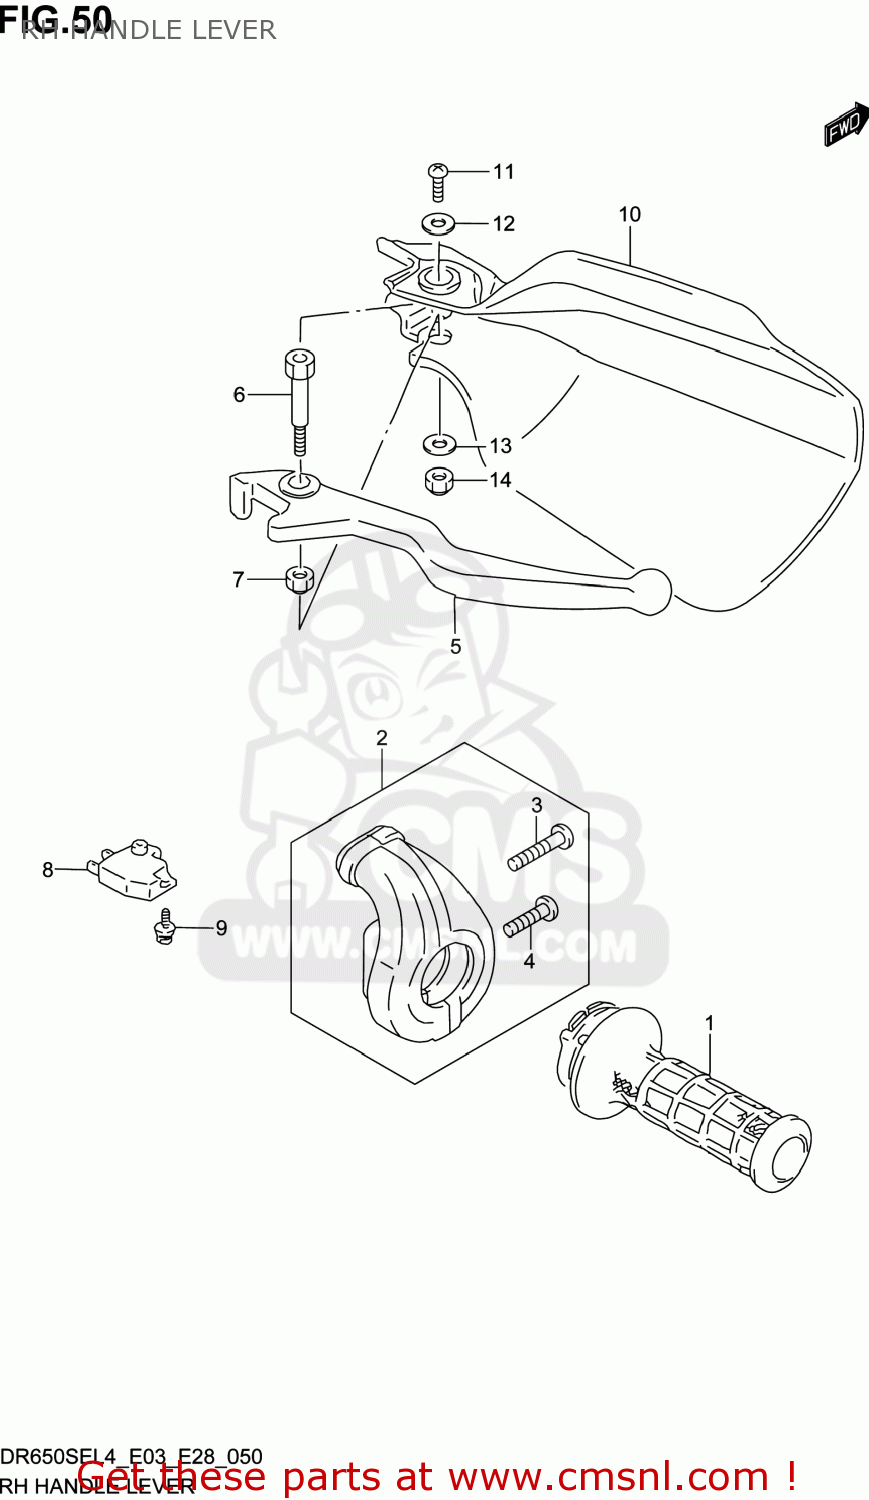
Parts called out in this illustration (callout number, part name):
1	GRIP,THROTTLE
2	CASE ASSY,THROTTLE
3	SCREW
4	SCREW
5	LEVER,BRAKE
6	BOLT,BRAKE LEVER PIVOT
7	NUT,LEVER PIVOT
8	SWITCH ASSY,FR BRAKE
9	SCREW
10	COVER,KNUCKLE,R
11	SCREW
12	WASHER(5.5X16X1.2)
13	WASHER(6.5X16X1.6)
14	NUT
